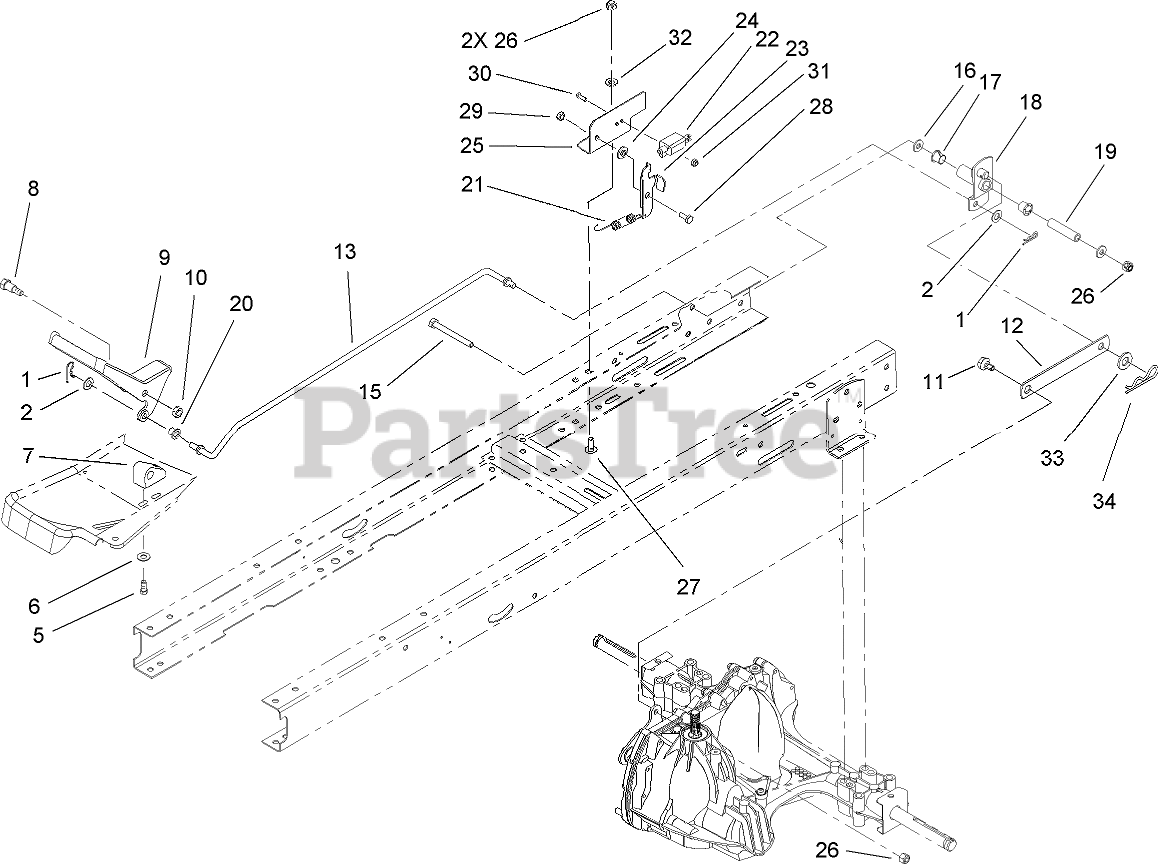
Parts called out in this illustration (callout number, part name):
1	PIN-COTTER
2	WASHER-FLAT
5	SCREW-PLASTITE
6	WASHER-FLAT
7	BLOCK-PIVOT
8	SCREW-SHOULDER, HH
9	PEDAL-CONTROL, SPEED
10	NUT-LOCK, NI
11	BOLT-SHOULDER
12	LINK-CONTROL, SPEED
13	ROD-CONTROL, SPEED
15	SCREW-HH
16	WASHER-FLAT
17	BUSHING-NYLINER
18	PIVOT ASM
19	SPACER-PIVOT
20	BUSHING-FLANGED
21	SPRING-EXTENSION
22	SWITCH-POLE, SINGLE
23	BRACKET-PIVOT
24	WASHER-STEPPED
25	BRACKET-ADJUSTMENT
26	NUT-LOCK, NI
27	SCREW-CARR
28	SCREW-HHF
29	NUT-LOCK, NI
30	SCREW-SHH
31	NUT-LOCK
32	WASHER-PLAIN
33	WASHER-FLAT
34	PIN-HAIR
